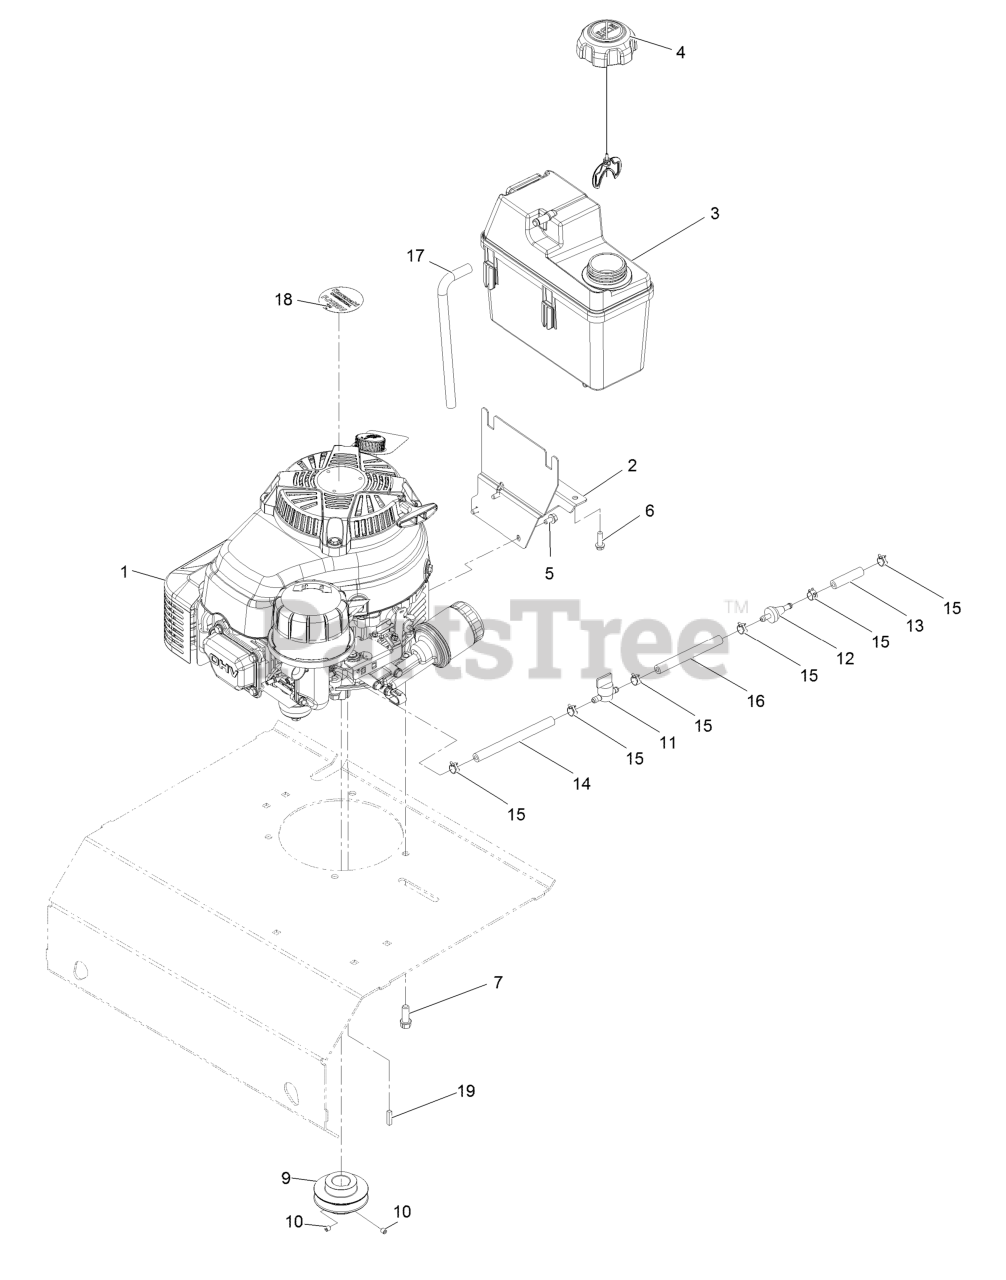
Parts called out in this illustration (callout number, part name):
1	Engine-Kawasaki
2	Mount-Tank
3	Tank-Fuel
4	Cap-Fuel
5	Screw-HWH M6-1 X 12Mm Tf
6	Screw-HWH 1/4-10 X .82 Plastite
7	Screw-HWH 3/8-16 X 1 Taptite
9	Pulley-Driver
10	Screw-Set HSH 1/4-28 X 1/4
11	Valve-Fuel
12	Filter-Fuel
13	Hose-Fuel
14	Hose-Fuel
15	Clamp-Hose
16	Hose-Fuel
17	Hose-Vent, Canister
18	Decal-Recoil
19	Key-3/16 X 3/16 X 7/8
